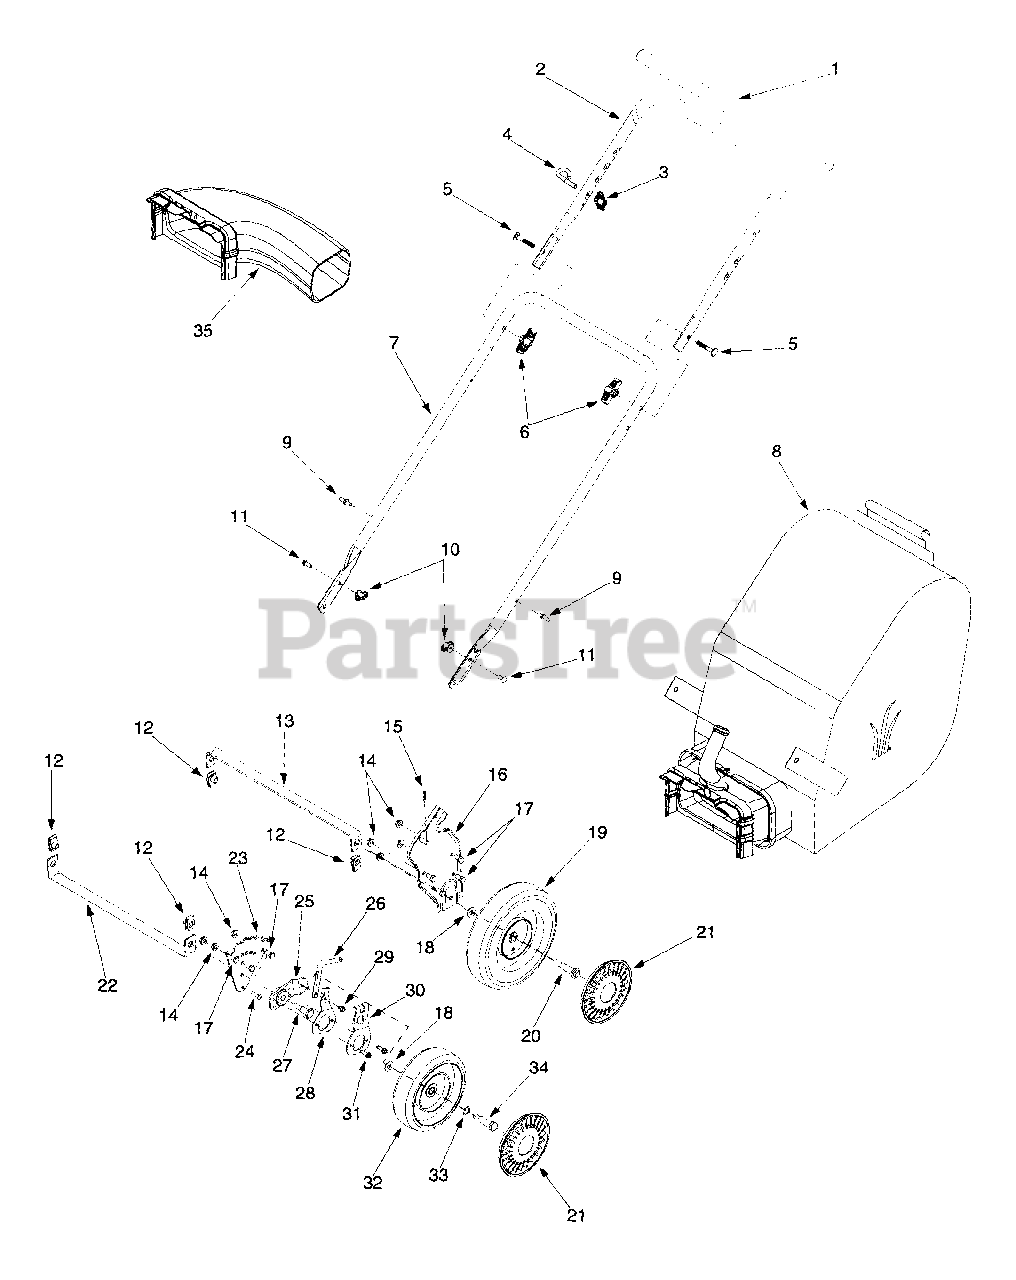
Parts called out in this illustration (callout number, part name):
1	Foam Grip
2	Upper Handle
4	Eye Bolt
5	Carriage Bolt
6	Handle Knob 5/16-18
8	Bag Only
9	Studs
10	Wing Nut 1/4-20
11	Carriage Screw 1/4-20 x 75
12	Lock U-Clip Nut 3/8-16
15	Cotter Pin
17	Hex Cap Screw 5/16-18 x .625
18	Roll Washer .401 ID x .870 OD
19	Wheel 9 x 2
20	Shoulder Screw 3/8-16
21	Hubcap
22	Front Wheel Support Brace
23	Height Bracket Adjuster LH
23	Height Bracket Adjuster RH
24	Screw #12-16 x 1.0
25	Pivot Arm
26	Handle Height Adjuster
27	Shoulder Screw 3/8-16
28	Height Adjuster Plate Spring
29	Hex Washer Screw 1/4-20 x .375
32	Wheel 7 x 2
33	Wave Washer .531 ID x .781 OD
34	Shoulder Screw
35	Blower Kit
